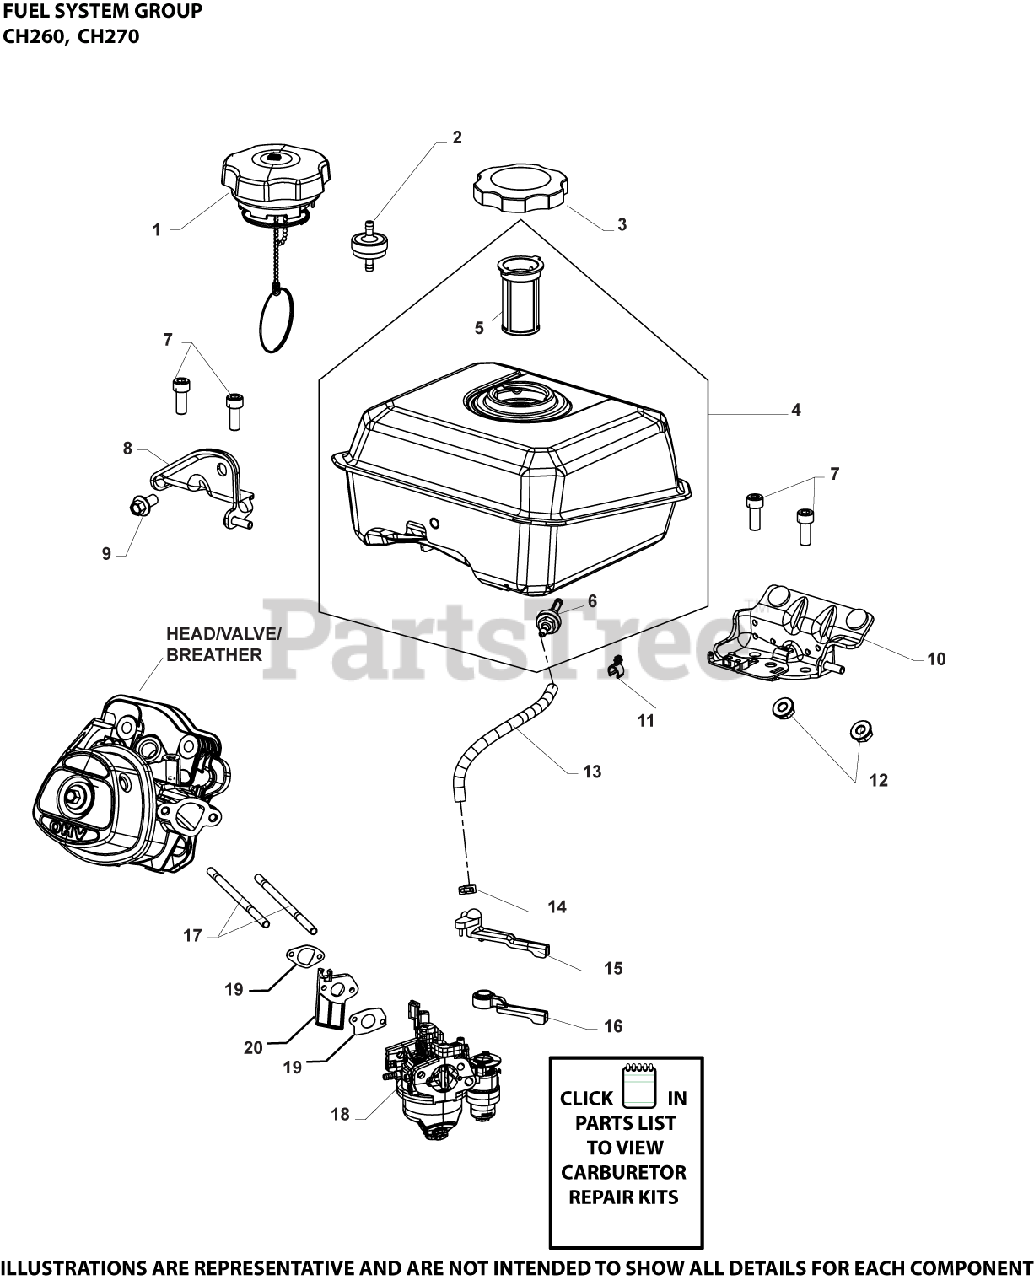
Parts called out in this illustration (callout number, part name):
3	CAP, FUEL TANK
4	TANK, ASSY FUEL
5	FILTER, FUEL TANK
6	FITTING, FUEL ASSY
7	SCREW, HEX SOCKET HD CAP (CKY)
8	BRACKET ASSY, FUEL TANK
9	SCREW, FLG 8X1.25X16
11	CLIP, FUEL HOSE
13	LINE, FUEL (10"-CUT TO LENGTH)
14	CLAMP, FUEL LINE
17	STUD, CARBURETOR
18	KIT, CARBURETOR ASSEMBLY
19	KIT, INTAKE GASKET
20	KIT, INSULATOR
